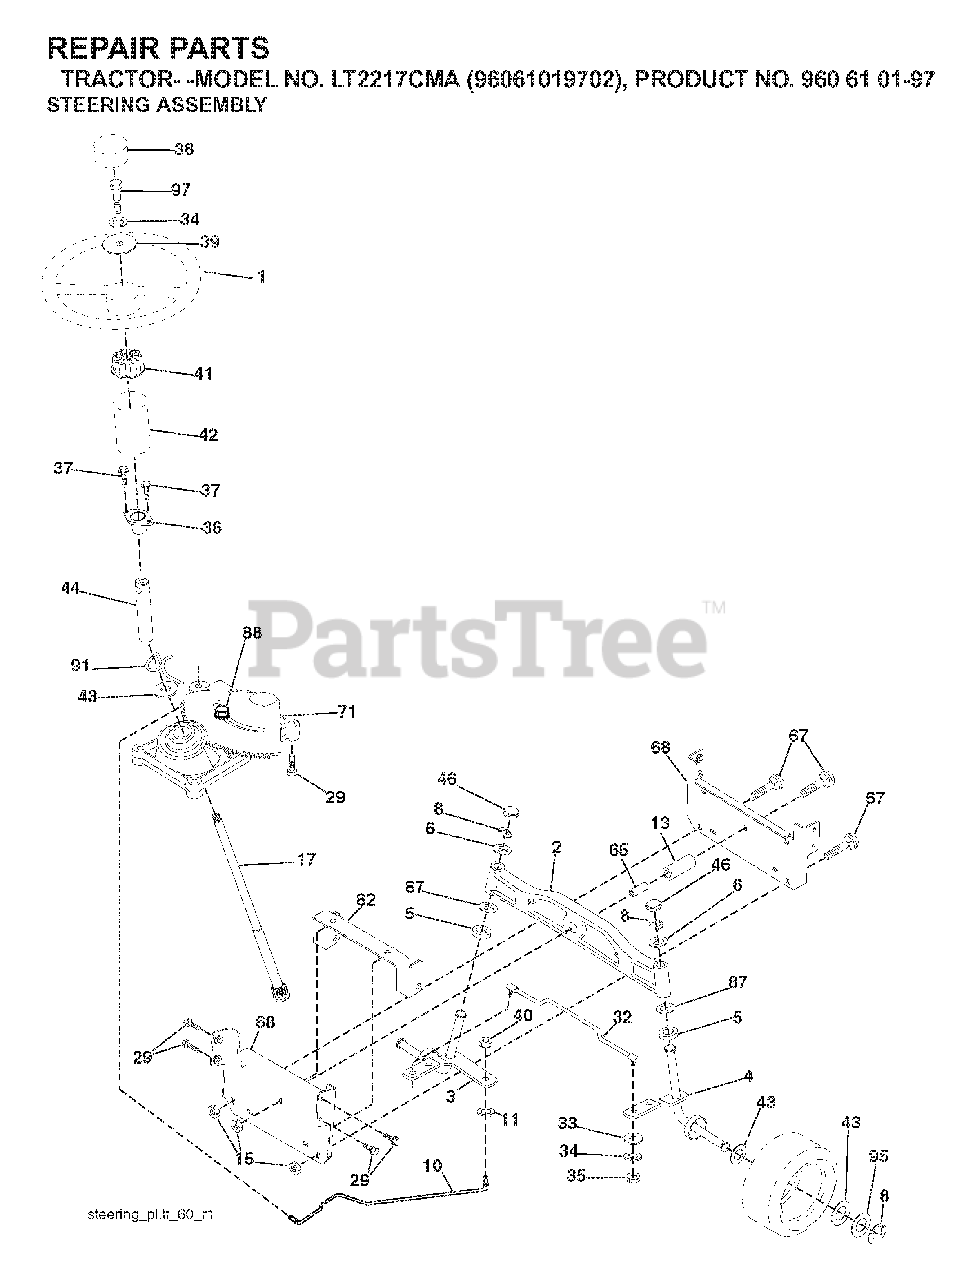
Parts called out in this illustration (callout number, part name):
1	WHEEL.STEERING.PREM.2.BLK
2	AXLE ASSY FRONT
3	SPINDLE.ASM.LH.15"TIRES
4	SPINDLE.ASM.RH.15"TIRES
8	RING CLIP
10	DRAGLINK.15".TIRES.2001
11	WASHER, LOCK 3/8
13	SPACER AXLE
15	NUT
17	SHAFT STEERING SPLINE
29	SCREW, 3/8-16X3/4
32	ROD.ASM.TIE.BALL.JOINT.NOVAN
33	WASHER M
34	LOCKWASHER
35	NUT, CROWNLOCK
36	BUSHING, STEERING
38	INSERT.CAP.STRG.WH.BLACK
39	WASHER.11/32
40	NUT CROWNLOCK 3/8-24
41	ADAPTER, WHEEL STNG..
42	BOOT.STEERING.SHAFT.BLACK
44	SHAFT.EXTEN.STRG.SPLINE
46	CAP.SPINDLE
65	SPACER BRACE AXLE
67	BOLT CARRIAGE
68	BRACE.AXLE.15"TIRES
71	STEERING ASM
82	BRACKET.SUSP.CHASSIS.FRONT.15
87	WASHER, FLAT .781 X 1 1/2"
88	BOLT, SHOULDER 7/16-20
91	CLIP.STEERING
95	WASHER.HARDENED
